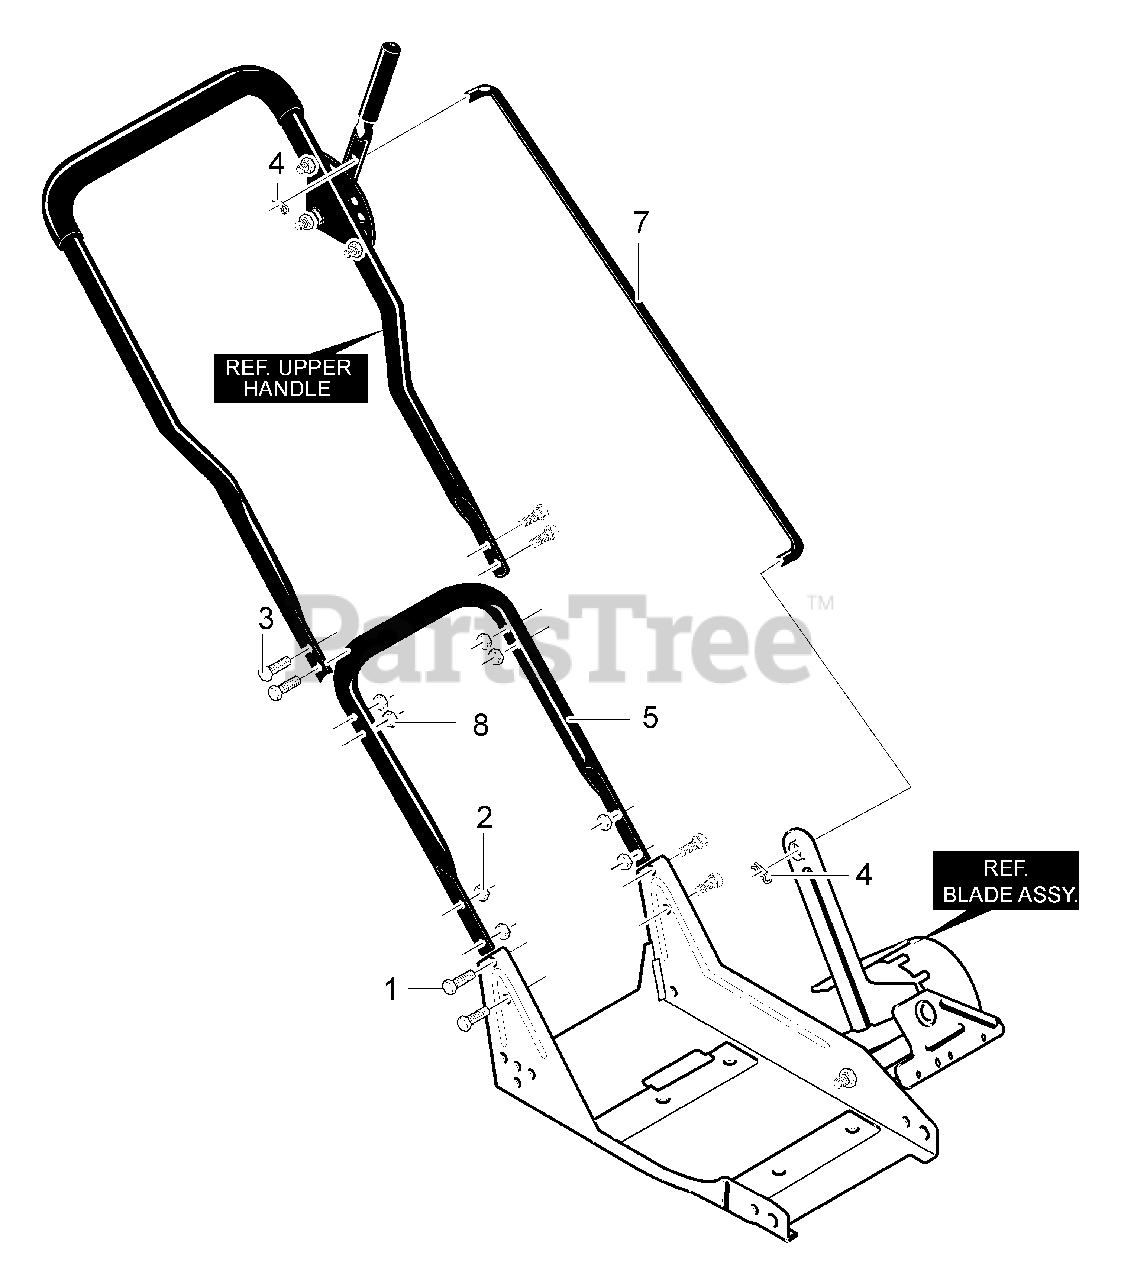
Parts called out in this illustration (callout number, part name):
1	Screw, 5/16-18x.63
2	Nut, 5/16-18
3	Bolt, 5/16-18x1.63
5	Lower Handle
7	Control Rod
8	Nut 5/16-18
